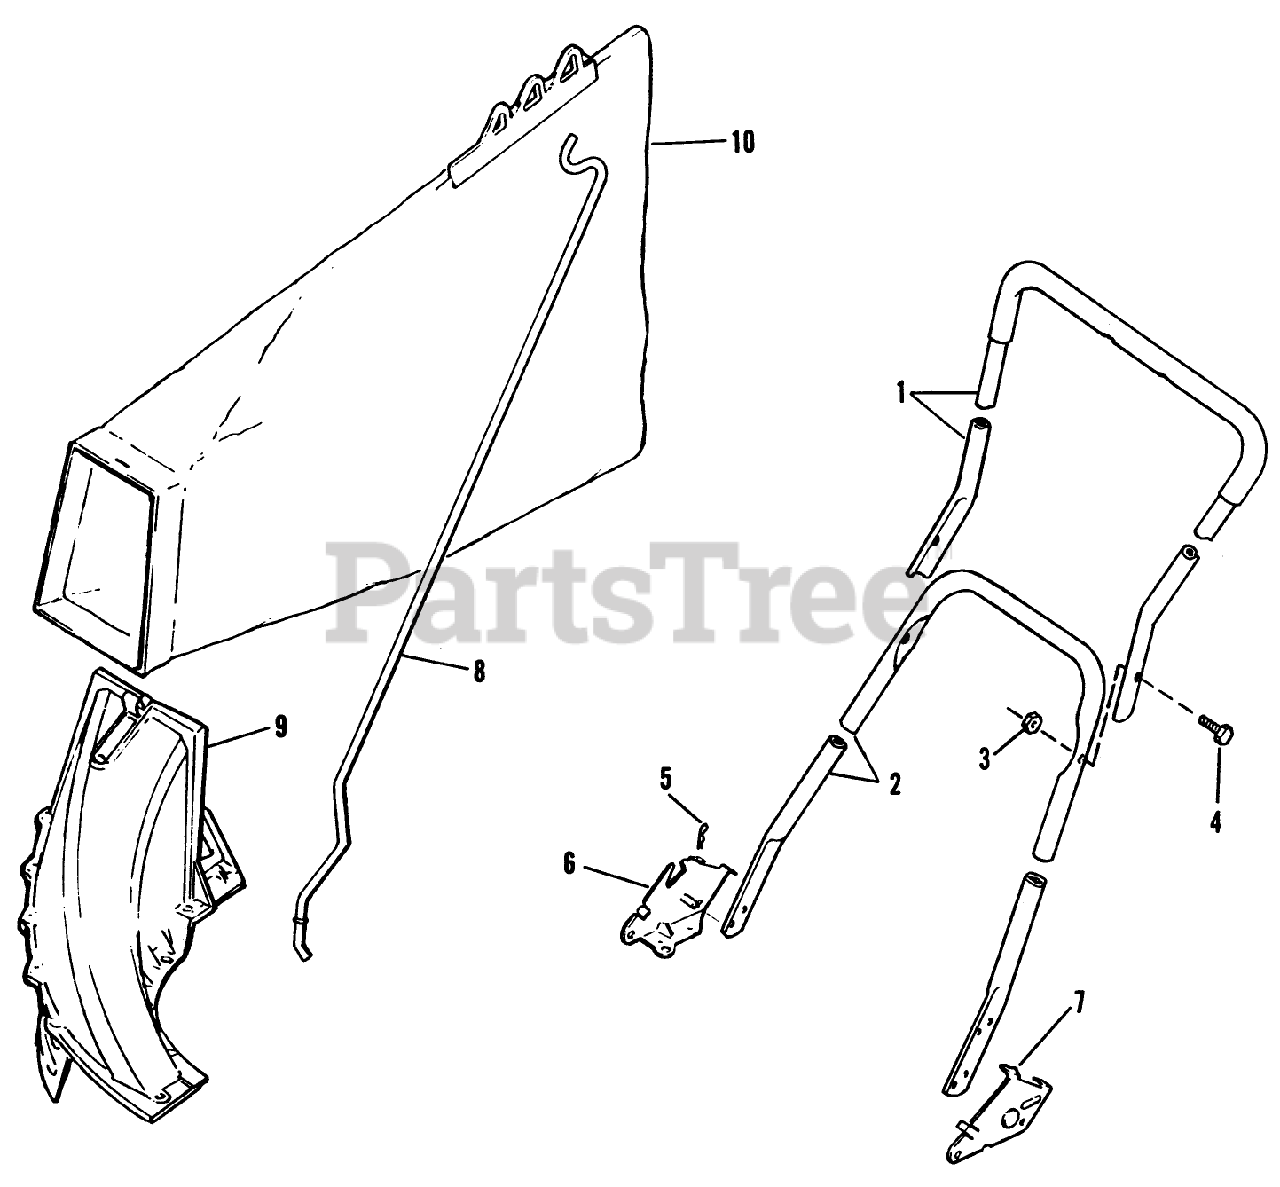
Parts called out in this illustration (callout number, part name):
2	Cover Plate
3	LOCKNUT E
5	HAIR PIN
8	ROD GRASSBAG
